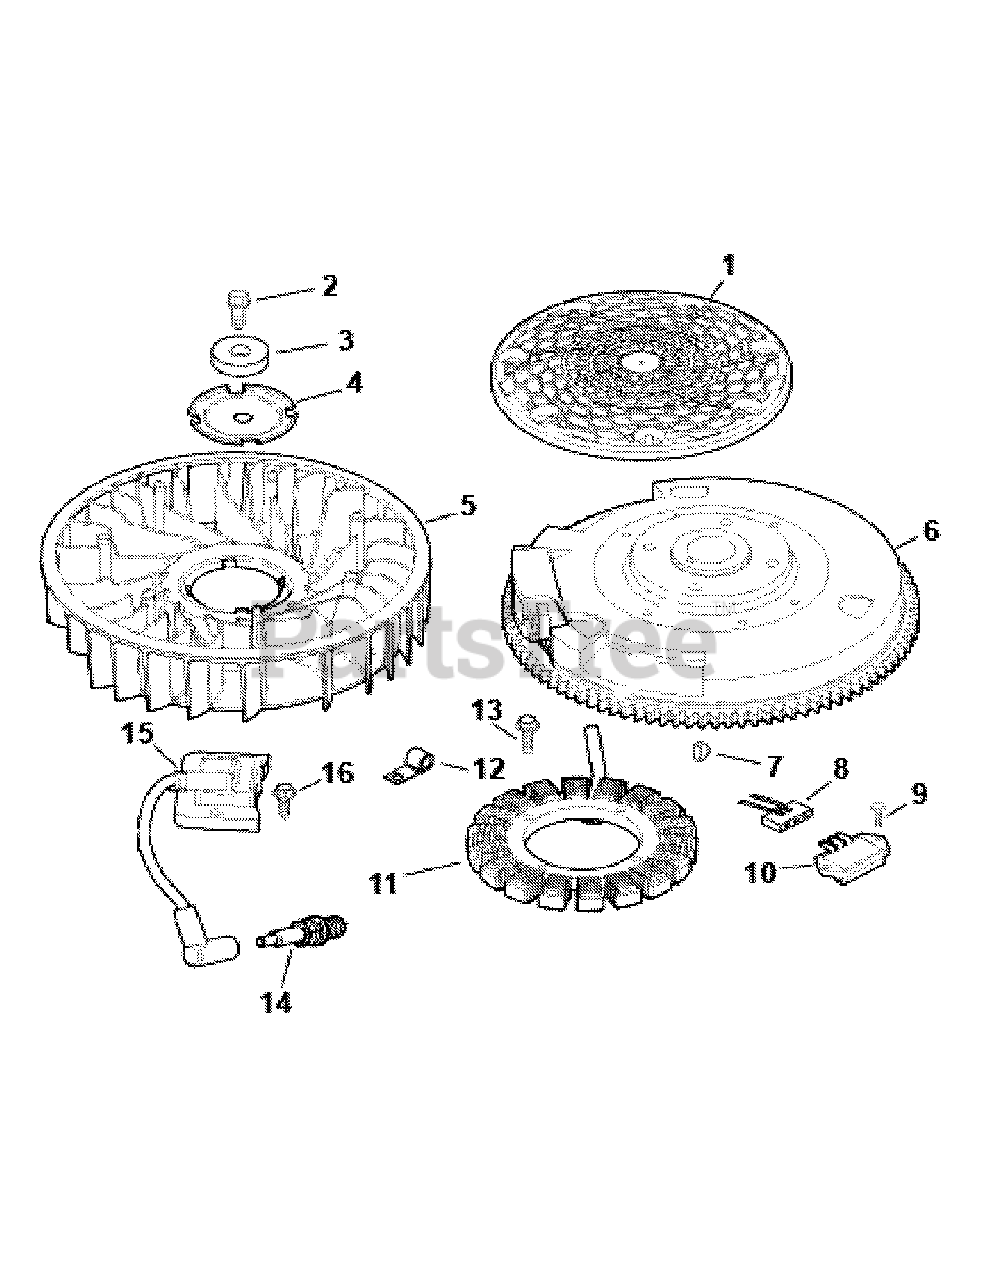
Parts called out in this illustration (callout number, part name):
2	Hex Flange Screw
3	Plain Washer 3/8"
4	Fan Mounting Plate
5	Fan
6	Flywheel
7	Flywheel Key
8	Connector
9	Heavy Hex Flange Screw
10	Voltage Regulator
11	15 Amp Stator Kit
12	Cable Clip
13	Hex Screw
14	Spark Plug
15	Ignition Module
16	Hex Flange Screw
